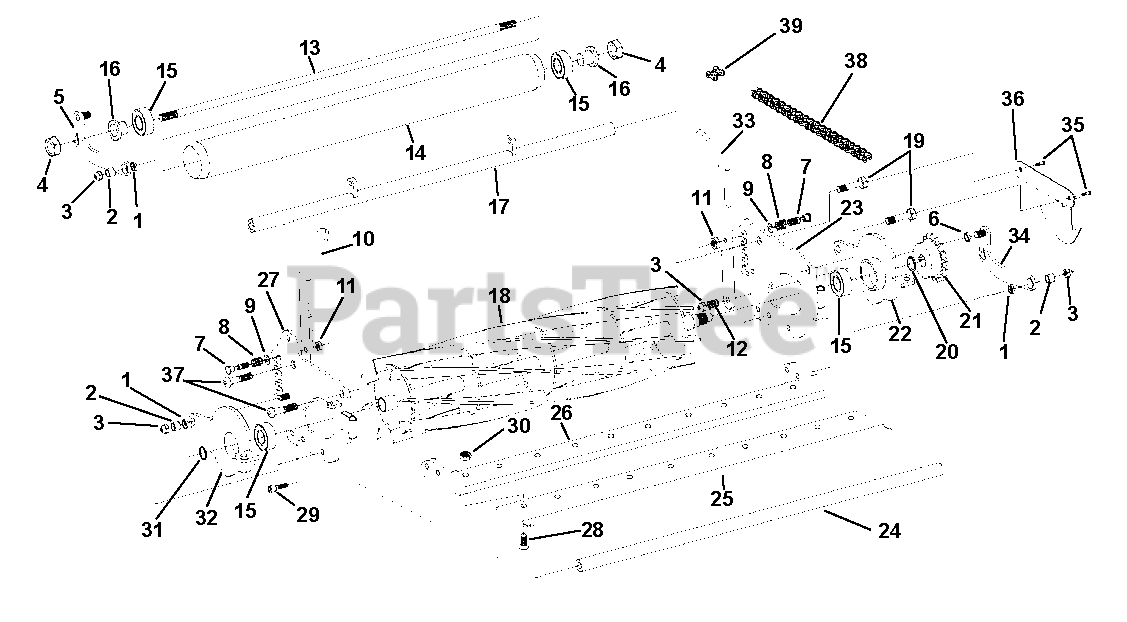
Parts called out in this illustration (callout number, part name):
1	Bushing, Sintered Steel, Oil Impregnated
3	Nut, .375-24 Nyloc Jam
4	Nut, Jam Nyloc .50-20
5	Arm, Rear Roller Height Right Hand
6	Bushing, 60 Degree
7	Pin, Quick Adjust
8	Spring, Quick Adjust
9	Washer, Quick Adjust
10	Handle, Quick Adjust Right Hand
11	Nut, Hex .312-24
13	Axle, Roller 25-Inch (995030, 032)
14	Tube, Roller 25-Inch (995030, 032)
15	Bearing 47 mm x 20 mm x 14 mm
17	Bar, Rear Spacer 25-Inch (995030, 032)
18	Reel, 25-Inch 6-Blade (995030, 032)
19	Cap Screw, Special, Hex Head .50-13 x 1.25
21	Sprocket, 17 Tooth
22	Housing, Bearing Left Hand
23	Side Plate, Left Hand
24	Bar, Spacer 25-Inch (995030, 032)
25	Bed Knife 25-Inch (995030, 032)
26	Weldment, Bedbar 25-Inch (995030, 032)
27	Side Plate Right Hand
28	Screw, Hex Socket Flat CSK Head .312 x 1
29	Cap Screw, Hex Socket Head .38-16 x .625 Stainless Stee
30	Nut, Hex Nyloc .312-18
31	Snap Ring, .75 External
32	Housing, Bearing Right Hand
33	Handle, Quick Adjust Left Hand
34	Arm, Rear Roller Height Left Hand
35	Screw, Pan Head Slotted, Stainless Steel .25-28
36	Chain Guard, Reel
37	Screw, Button Head .50-13 x 1
38	Chain, Reel Drive (56" # 423)
39	Master Link
